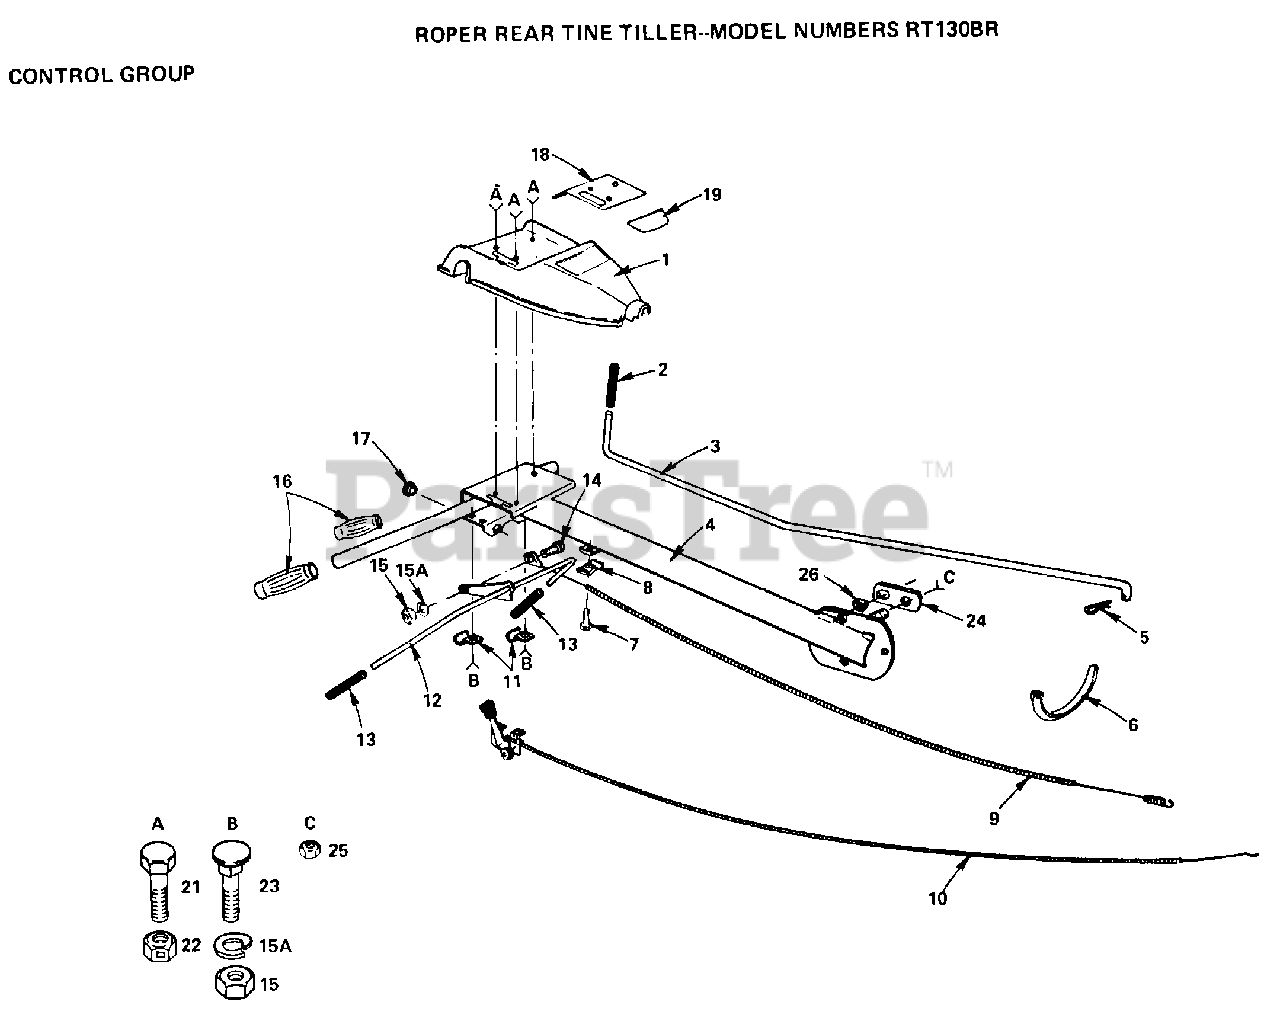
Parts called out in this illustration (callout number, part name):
1	PANEL - CONTROL
2	GRIP TI
5	RETAINER M
6	TIE CABLE CRT
7	SCREW TI
8	CONDIUT CLIP T
9	CABLE.CLUTCH.CRT
13	GRIP BAR CRT
14	SHOULDER BOLT ST
15A	LOCKWASHER
17	GROMMET TI
19	DECAL - CONTROL PANEL
23	BOLT
24	"NUT, LOCK CRT"
25	LOCKNUT
26	NUT FLANGE CRT
